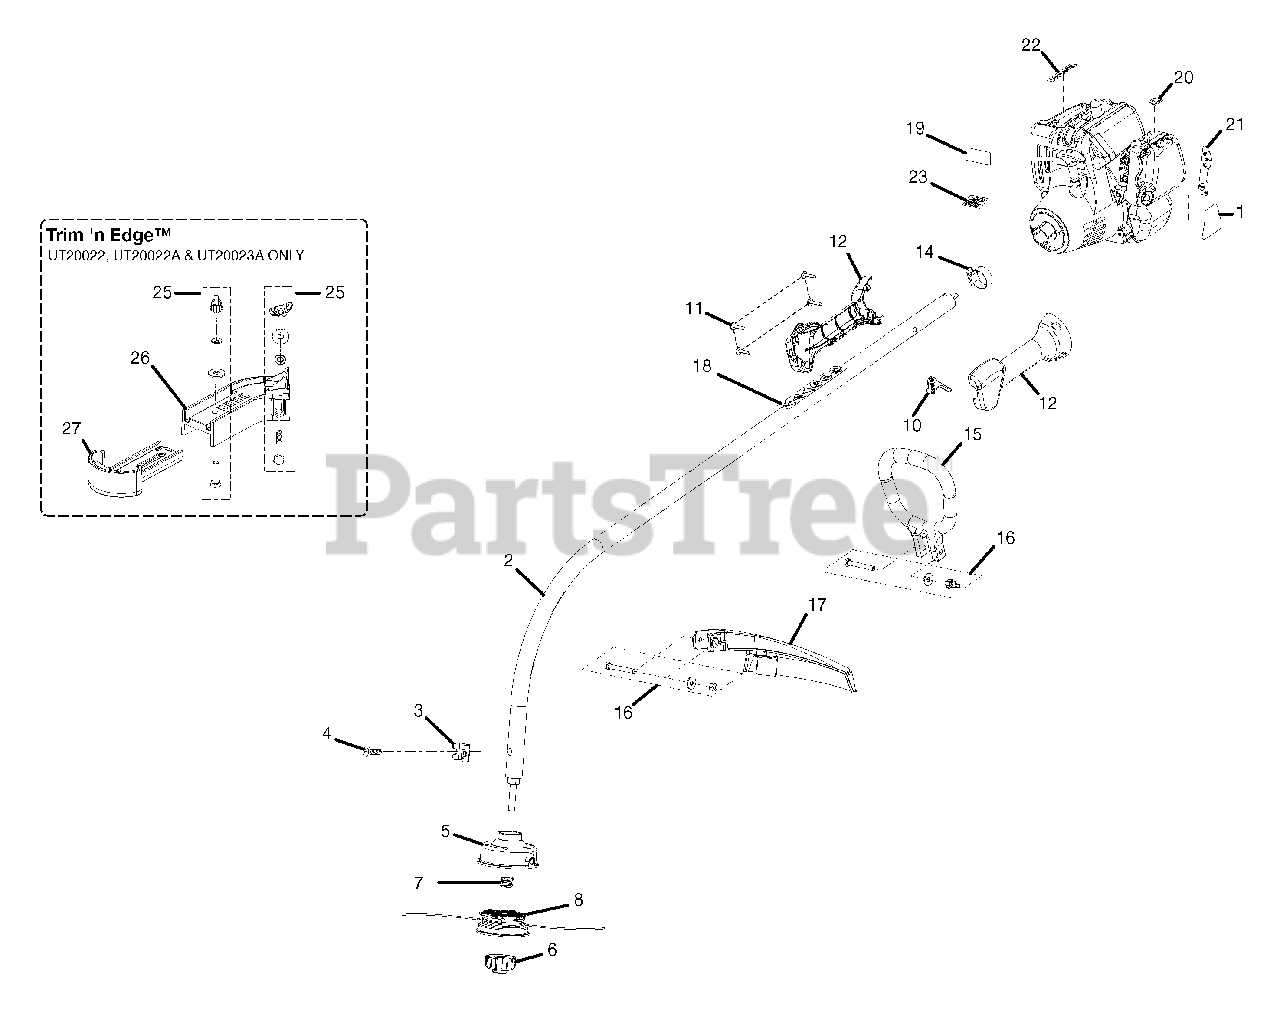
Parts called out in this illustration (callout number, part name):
1	STARTING INSTRUCTION DECAL
2	CURVED SHAFT ASSEMBLY
3	CLAMP
4	SCREW (10-32 x 3/8 in.)
5	HOUSING AND EYELET
6	SPOOL RETAINER (RH)
7	COMPRESSION SPRING
8	SPOOL W/LINE
10	TRIGGER
11	SCREW (10-14 x 7/8 in. TRUSS HD.)
12	HANDLE GRIP ASSEMBLY
14	BOOM CLAMP
15	FRONT HANDLE
16	FASTENER PARTS KIT
17	GRASS DEFLECTOR ASSEMBLY
18	DECAL, WARNING/STARTING BOOM
19	DECAL, TRIMLITE LOGO .
20	DECAL, PRIMER
21	DECAL, CHOKE
22	DECAL, HOMELITE
23	LABEL, ZIP START
25	FASTENER PARTS KIT
26	EDGER BASE
27	EDGER GUIDE
